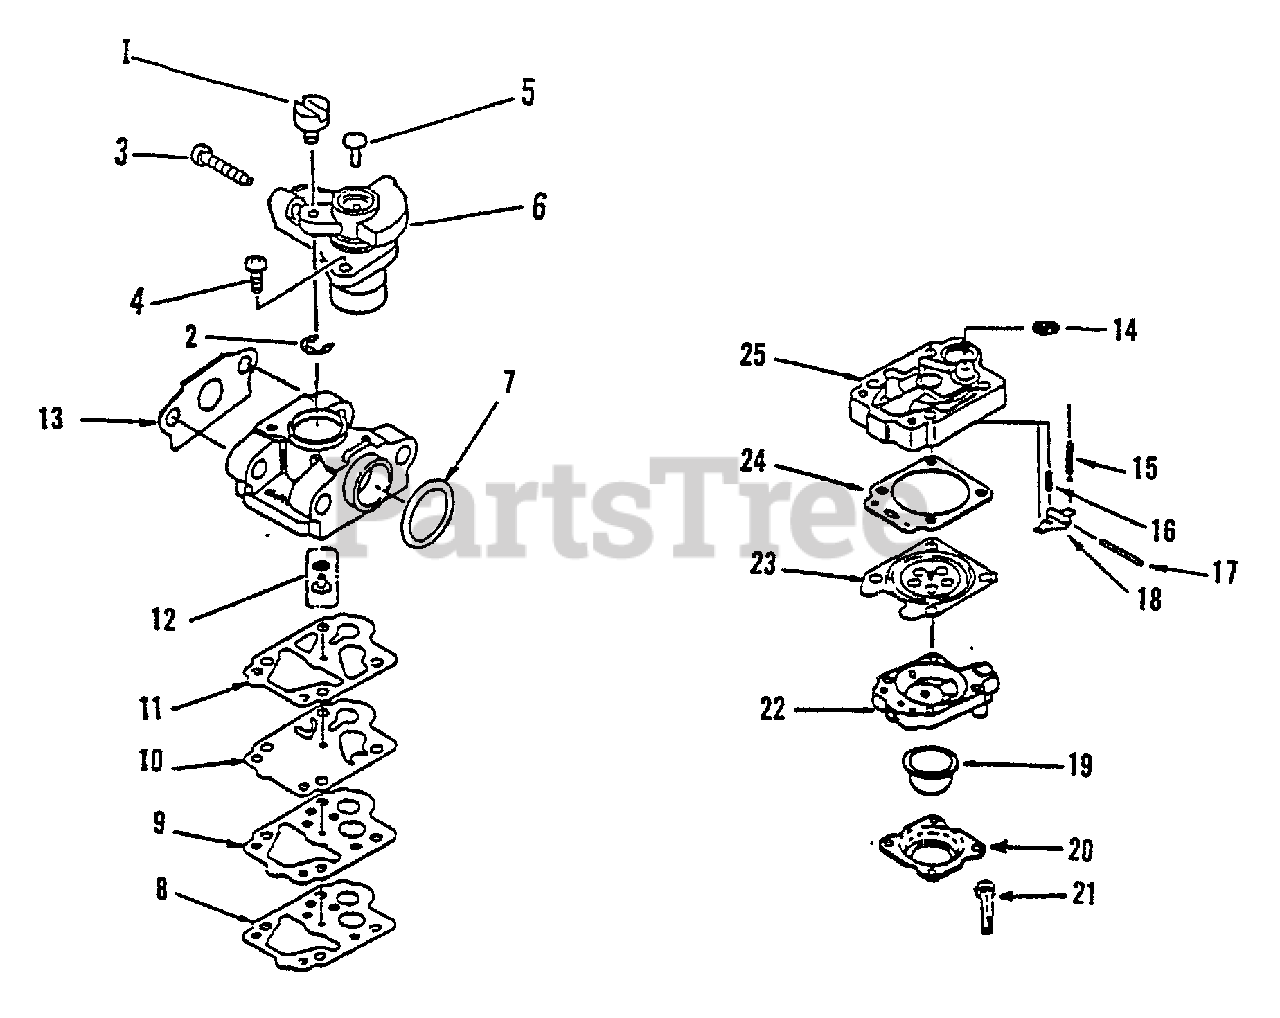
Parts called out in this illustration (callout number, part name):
4	SCREW, THROTTLE COLLAR
6	THROTTLE VALVE ASSY
8	GASKET, PLATE
9	COVER, PUMP
12	KIT, MAIN JET
14	STRAINER
15	VALVE, INLET NEEDLE
17	PIN, METERING LEVER
18	LEVER, METERING
19	BULB, PURGE
20	RETAINER, PURGE BULB
22	BODY ASSY, PURGE
23	DIAPHRAGM, METERING
24	GASKET, METERING
25	BASE, PURGE
